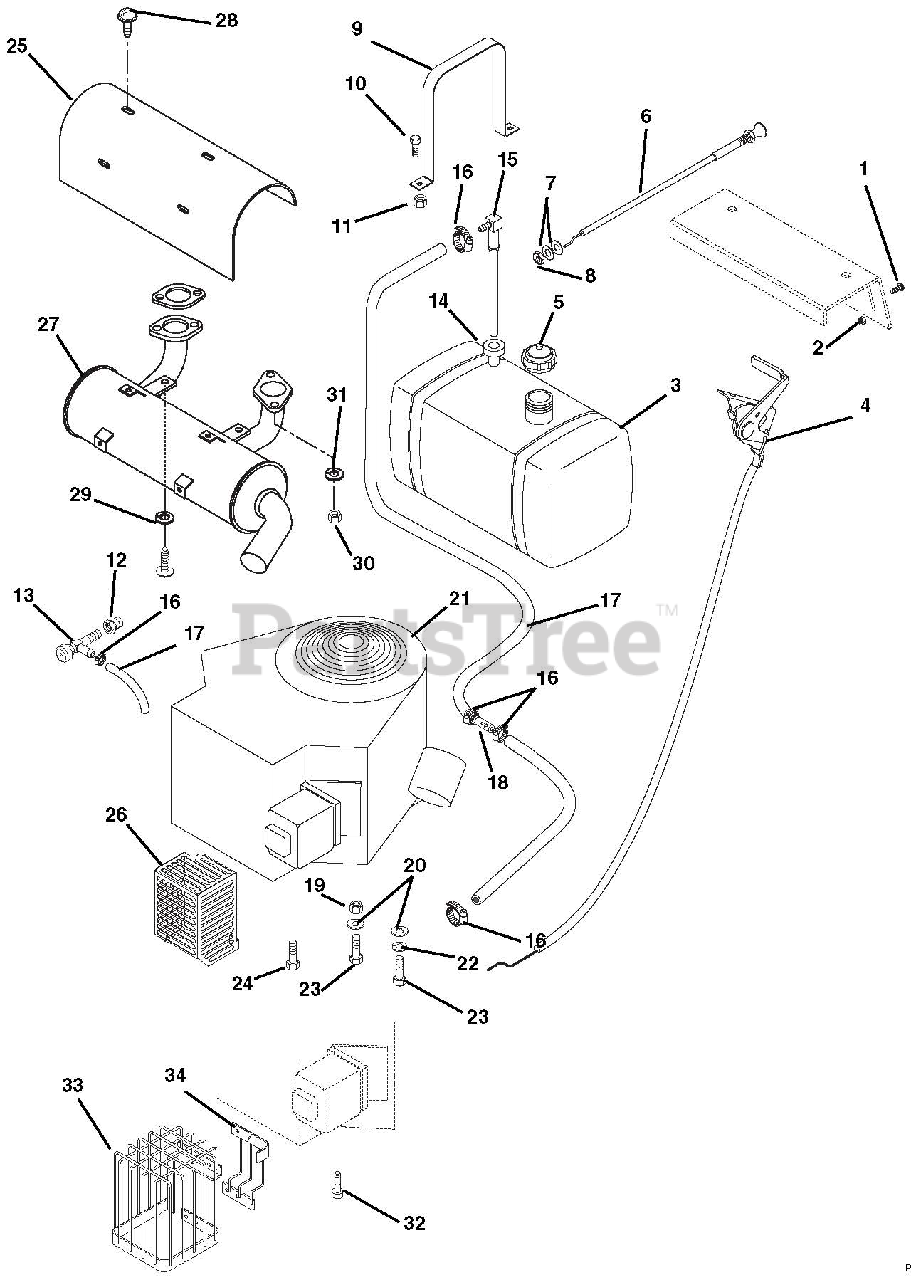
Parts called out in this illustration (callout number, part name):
1	Screw-Machine 10-32 x .50
2	Nut-Locking-Nylon 10-24 with Insert
3	Fuel Tank
4	Cable, Throttle Control
5	Cap-Fuel Tank
6	Control, Choke
6	Cable, Choke
7	Washer-Flat-Steel .406 x .812 x .065
8	Nut-Jam .38-24
9	Strap-Fuel Tank
10	Bolt-Hex .25-20 x .50 Grade 5
11	Nut-Locking-Center .25-20
12	Adapter, Oil Drain
13	Drain-cock, Oil
14	Bushing
15	Fitting, Tank
16	Hose Clamp
17	Gas Line-Bulk 1/4 inch ID
18	Filter, Fuel
19	Nut-Locking-Nylon .31-18
20	Washer-Flat-Steel .344 x .688 x .065
21	Engine-14 HP Kawasaki
21	Engine Briggs and Stratton 16HP Twin
21	Engine-18 HP Robin
22	Washer-Lock .313 x .078
23	Bolt-Hex M8 x 1.25 x 30 mm
23	Bolt-Hex M8 x 1.25 x 30
24	Bolt -Hex .31-18 x 1.75
25	Shield-Heat
26	Weldment, Muffler Guard
27	Muffler
28	Screw-Tapping M6-1 x 25
29	Screw-Machine 8MM-1.25 x 20
30	Nut-Hex M8-1.25
31	Washer-Lock .31 x .078
32	Screw-Socket Head M8 x 1.25 x 20
33	Weldment, Muffler Guard
34	Weldment, Muffler Guard
